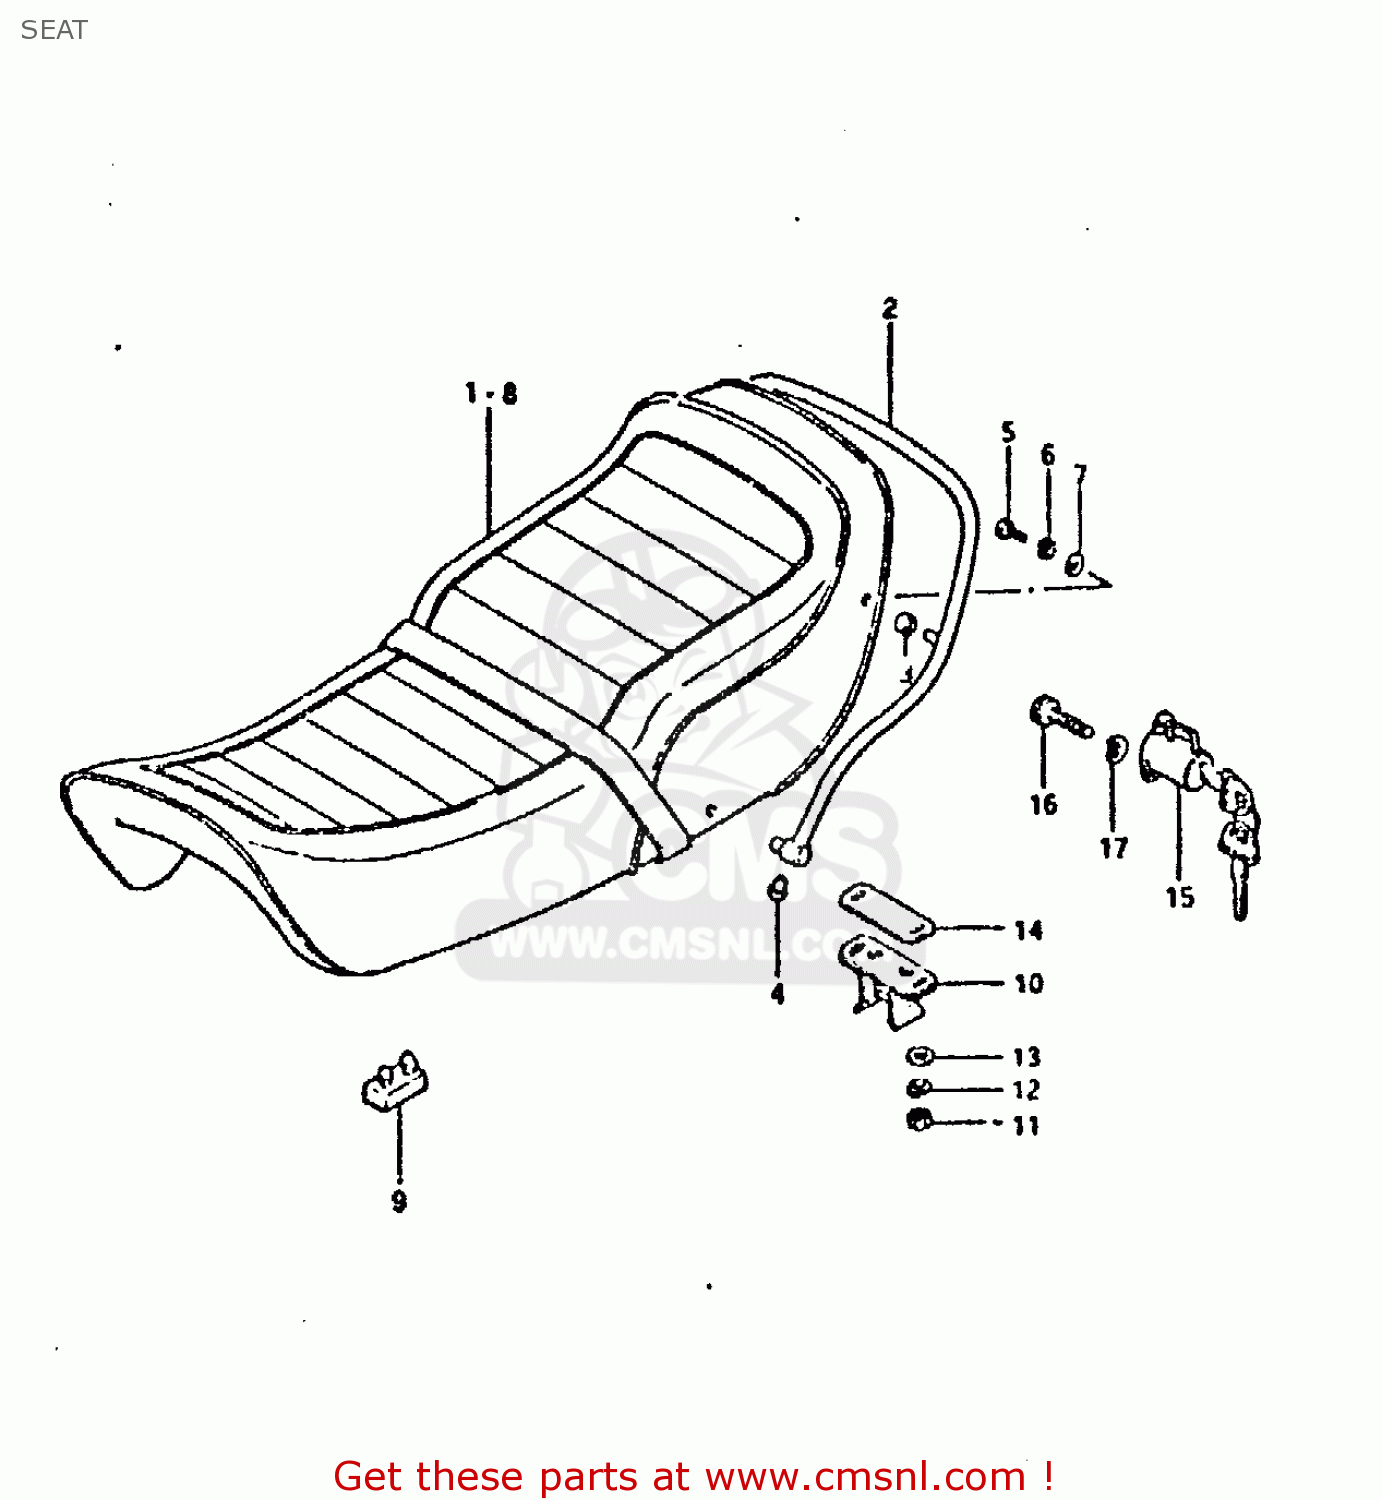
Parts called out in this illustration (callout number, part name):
1	SEAT ASSY (BLACK)
2	HANDLE,PILLION RIDER
3	CUSHION
4	END,SHEET HANDLE
5	BOLT
6	LOCK WASHER
7	WASHER
9	CUSHION
10	STRIKER, SEAT LOCK
11	NUT 6MM
12	LOCK WASHER
13	WASHER
14	SHIM,SEAT LOCK STRIKER
15	LOCK ASSEMBLY,HELMET
16	BOLT
17	LOCK WASHER
